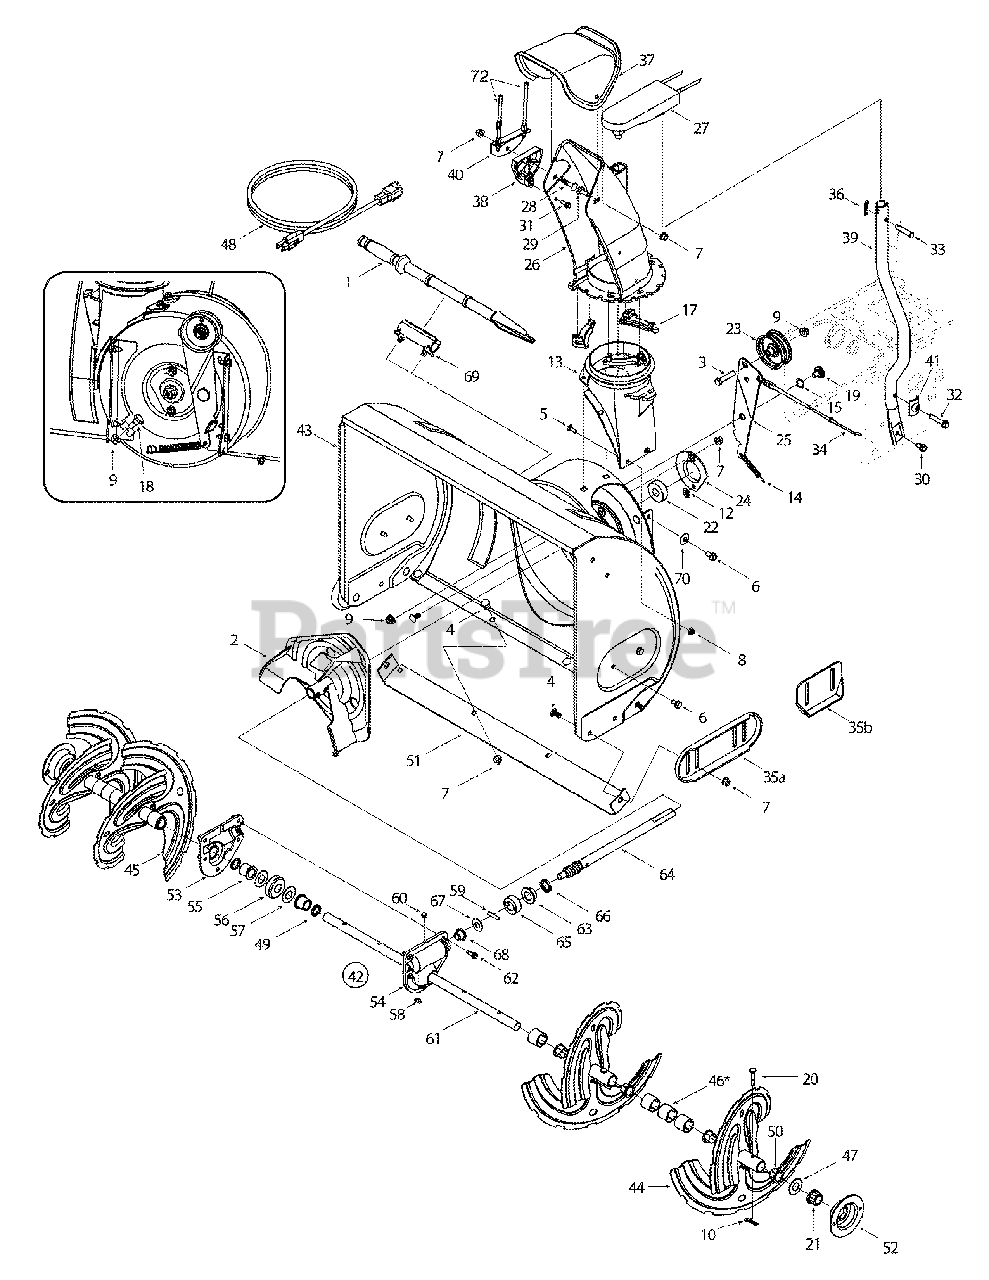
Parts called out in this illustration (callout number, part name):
1	Removal Tool, Snow
3	Screw, 3/8-16 x 1.75, Gr5, Std
4	Bolt, Carriage, 5/16-1 8 x.750 Gr1
5	Screw, Carriage, 1/4-20 x .75, Gr5
6	Screw, 5/16-12 x 0.750
7	Nut, Flange Lock, Nylon, 5/16-18, Gr F
8	Nut, Flange Lock, Nylon, 1/4-20, Gr F
9	Nut, Flange Lock, Nylon, 3/8-16, Gr F
10	Cotter Pin, Bow-Tie
11	Cable, Tie, 3/16 x .05 x 7.4
12	Nut, Push-on, .2 5 Dia
13	Chute, Adapter 5" Dia
14	Spring, Extension,.38 OD x 3.6
15	Washer, Wave, .625 x .885 x.015
16	Washer, Flat, .25 x .630 x .0515
17	Keeper, Flange
18	Screw, Shoulder, 4.98 x .340, 3/8-16
19	Screw, Shoulder, .625 x .17, 3/8-16
20	Pin, Shear, .25 x 1.50, Gr2
21	Bearing, Hex Flange x .75 ID
22	Bearing, Ball, 7.5 ID x 1.85 OD
23	Pulley, Idler, Flat 2.75 OD
24	Housing, Bearing, 1.85 ID
26	Chute Assembly, Lower, 4-way
27	Control Head Kit
28	Bolt, Carriage, 5/16-1 8, 1.50, Gr2
29	Bolt, Carriage, 5/16-1 8, 1.00
30	Screw, 5/16-12 x 0.75
31	Screw, 1/4-15x 0.75
32	Screw, Self-tapping 5/16-18x 1.75
33	Pin, Clevis, 3/8 x 1.75
34	Auger Clutch Cable, 44.75"
36	Pin, Cotter, .072 Dia. x 1.13
37	Upper Chute, Remote
38	Cable Guide, Chute Tilt
41	Tab, Handle
42	Gearbox Assembly, Auger, 24"
42	Gearbox Assembly, Auger, 26"
42	Gearbox Assembly, Auger, 28"
42	Gearbox Assembly, Auger, 30"
46	Spacer, 1.25 OD x .75 ID x 1.00
47	Washer, Flat, .76 x 1.49 x .0 6
48	Extension Cord, 3-Prong
49	Seal, Oil, .750 ID
50	Bushing, Flange, .800 ID x .910 OD
53	Housing, Auger, RH Reducer
54	Housing, Auger, LH Reducer
55	Bearing, Flange, .75 ID x 1.00 OD x .975
56	Gear, Worm 20T
57	Washer, Flat, .7 60 ID x 1.5 OD
58	Key, Hi-pro 3/16 x 5/8
59	Pin, Dowel,. 25 OD x 1.2
60	Plug, 1/4 x .437
61	Axle, Auger, 24"
61	Axle, Auger, 26"
61	Axle, Auger, 28"
61	Axle, Auger, 30"
62	Screw, Self-tapping, 1/4-20, 0.750
63	Bearing, Flange, .75 ID x 1.00 OD x .5 9
64	Shaft, Worm .75 OD
65	Collar, Thrust
66	Seal, Oil, .75 x 1 x .131
67	Washer, Flat, .5 1 x 1.12
68	Bearing, Flange, .75 ID x 1.00 OD x .925
69	Mount, Clean Out Tool
70	Washer, Bell, 3.40 x 872 x .060
72	Cable, Chute Deflector
